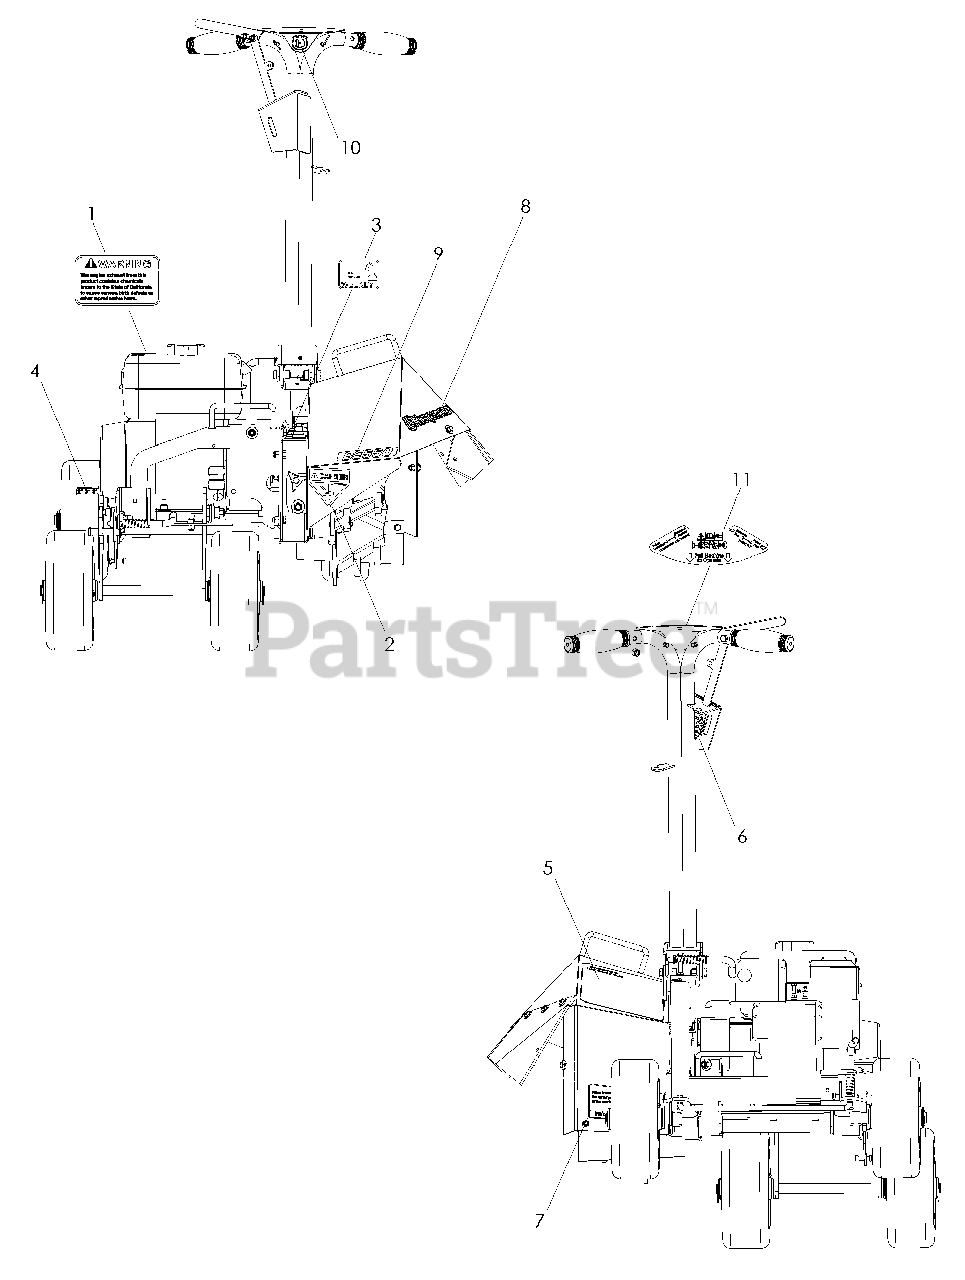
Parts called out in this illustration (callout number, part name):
1	DECAL, PROP 65
2	DECAL, DANGER FOOT
3	DECAL, OILING
4	DECAL, DEPTH
5	DECAL, INSTRUCTION
6	DECAL, PATENT PENDING
7	DECAL, GUIDELINE
8	DECAL, HUSQ HOOD
9	DECAL, BE550
10	DECAL, CROWN
11	DECAL, OPERATION
